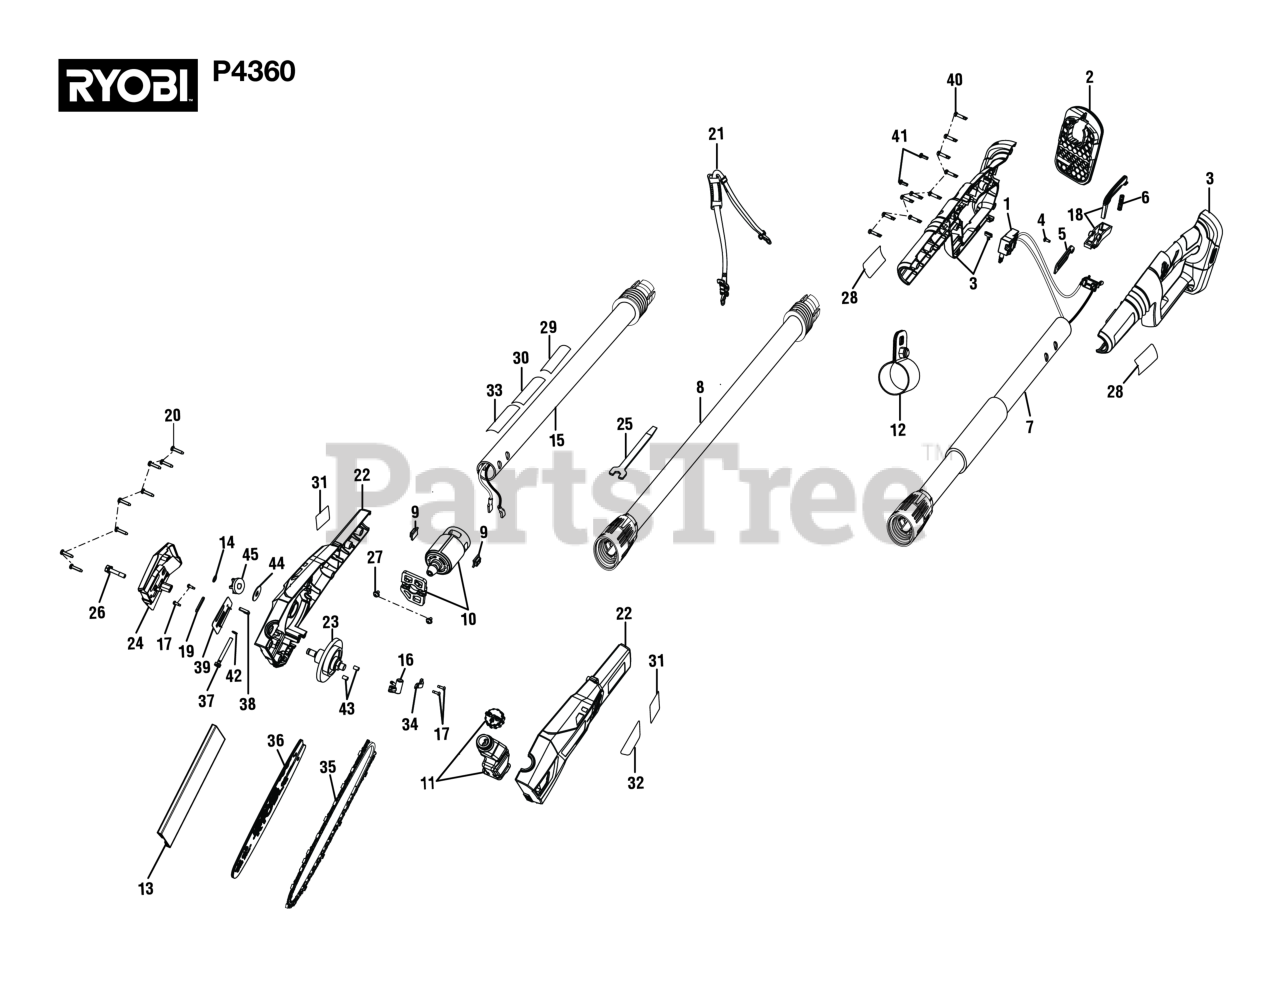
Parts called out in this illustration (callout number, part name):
1	Switch Assembly
2	18v Battery Foot
3	Handle Assembly
4	Screw (M3 x 8 mm)
5	Strap Hanger
6	Compression Spring
7	Lower Pole Assembly
8	Middle Pole Assembly
9	Rubber Bumper
10	Motor Assembly
11	Oil Tank And Cap Assembly
12	Clamp Assembly
14	Retaining Ring
15	Top Pole Assembly w/Labels
17	Screw (M3 x 10 mm)
18	Rear Trigger & Lock Button Assembly
19	Oil Outlet Seal Ring
20	Screw (M4 x 18 mm, T20 Torx Pan Hd.)
21	Harness Assembly
22	Housing Assembly (Inc. Key Nos. 31-32)
23	Output Shaft Assembly
24	Sprocket Cover Assembly
26	Screw with Spring Washer (M6 x 35 mm)
27	Screw w/Washer (M4 x 8 mm)
28	40V Lithium Label (Right)
29	Warning Icon Label
30	Warning Label (French/Spanish)
31	Logo Label
32	Data Label
33	Warning Label (English)
34	Pump Clamp
35	8 in. Saw Chain
36	Guide Bar
37	Adjustment Bolt (M5 x 46.5 mm)
38	Adjustment Guide Bar
39	Guide Bar Plate
40	Screw (M4 x 18 mm, T20 Torx Pan Hd.)
41	Screw (M4 x 11 mm, T20 Torx Pan Hd.)
42	Retaining Ring (4 mm)
43	Contact Plate Stopper
44	Cover Plate (Internal "D" Washer)
